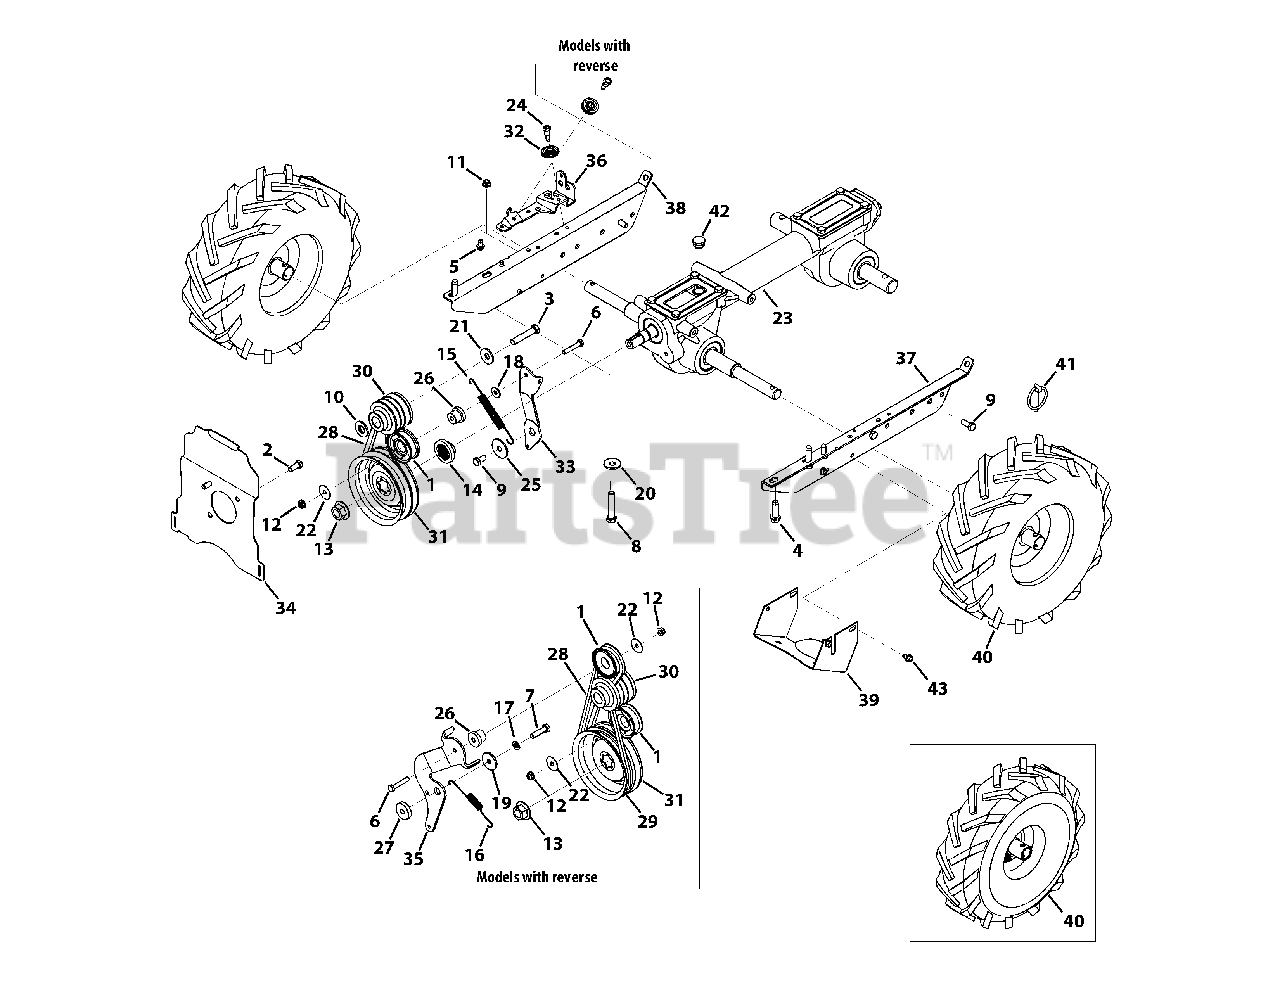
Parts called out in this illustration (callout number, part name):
1	Idler Pulley Assembly, 1.917 OD
2	Hex Head Screw, 5/16-24 x .625
3	Hex Head Screw, 3/8-24 x 2.00
4	Screw, 3/8-16 x 1.250
5	Screw, 1/4-20 x 0.500
6	Hex Head Screw, 1/4-20 x 1.50
7	Hex Head Screw, 5/16-24 x 1.25
8	Hex Head Screw, 5/16-18 x 1.50, B&S
9	Hex Head Screw, 5/16-18 x .75, Patch
10	Washer, Flat, .760 x 1.50 x .120
11	Flangelock Nut, 5/16-18, B&S
12	Flangelock Nut, 1/4-20
13	Flange Nut, 9/16-18
14	Pulley Hub, 5/8 SPLINE
15	Extension Spring, .480 OD x 5.00 LG
16	Extension Spring, LT5 PTO
17	Washer, Lock, 5/16
18	Washer, Flat, .28 x .74 x .063
19	Washer, Flat, .330 x 1.25 x .120
20	Washer, .396 x 1.140 x .095, B&S
21	Washer, Bell, .396 x 1.140 x .095
22	Washer, Flat, .265 x 1.0 x .030
23	Transmission Assembly
24	Screw, Shoulder, 1/4-28 x .342 x .335
25	Forward Idler Pivot Spacer
26	Spacer, Shoulder, .260 x .785 x .538
27	Reverse Idler Pivot Spacer
28	V Belt, 4L x 25.375 LG
29	V Belt, 3L x 29.125 LG
30	Engine Pulley, 3L & 4L, Honda
31	Transmission Pulley
32	Cable Roller
33	Forward Idler Bracket
34	Cover Mounting Plate
35	Reverse Idler Bracket
36	Pulley Mounting Bracket
37	LH Mount Frame
38	RH Mount Frame
39	Pulley Shield
40	Wheel Assembly, 11 x 4-4
41	Klik Pin, .25 DIA x 1.56
43	Self Tapping Screw, 1/4-14 x .625
